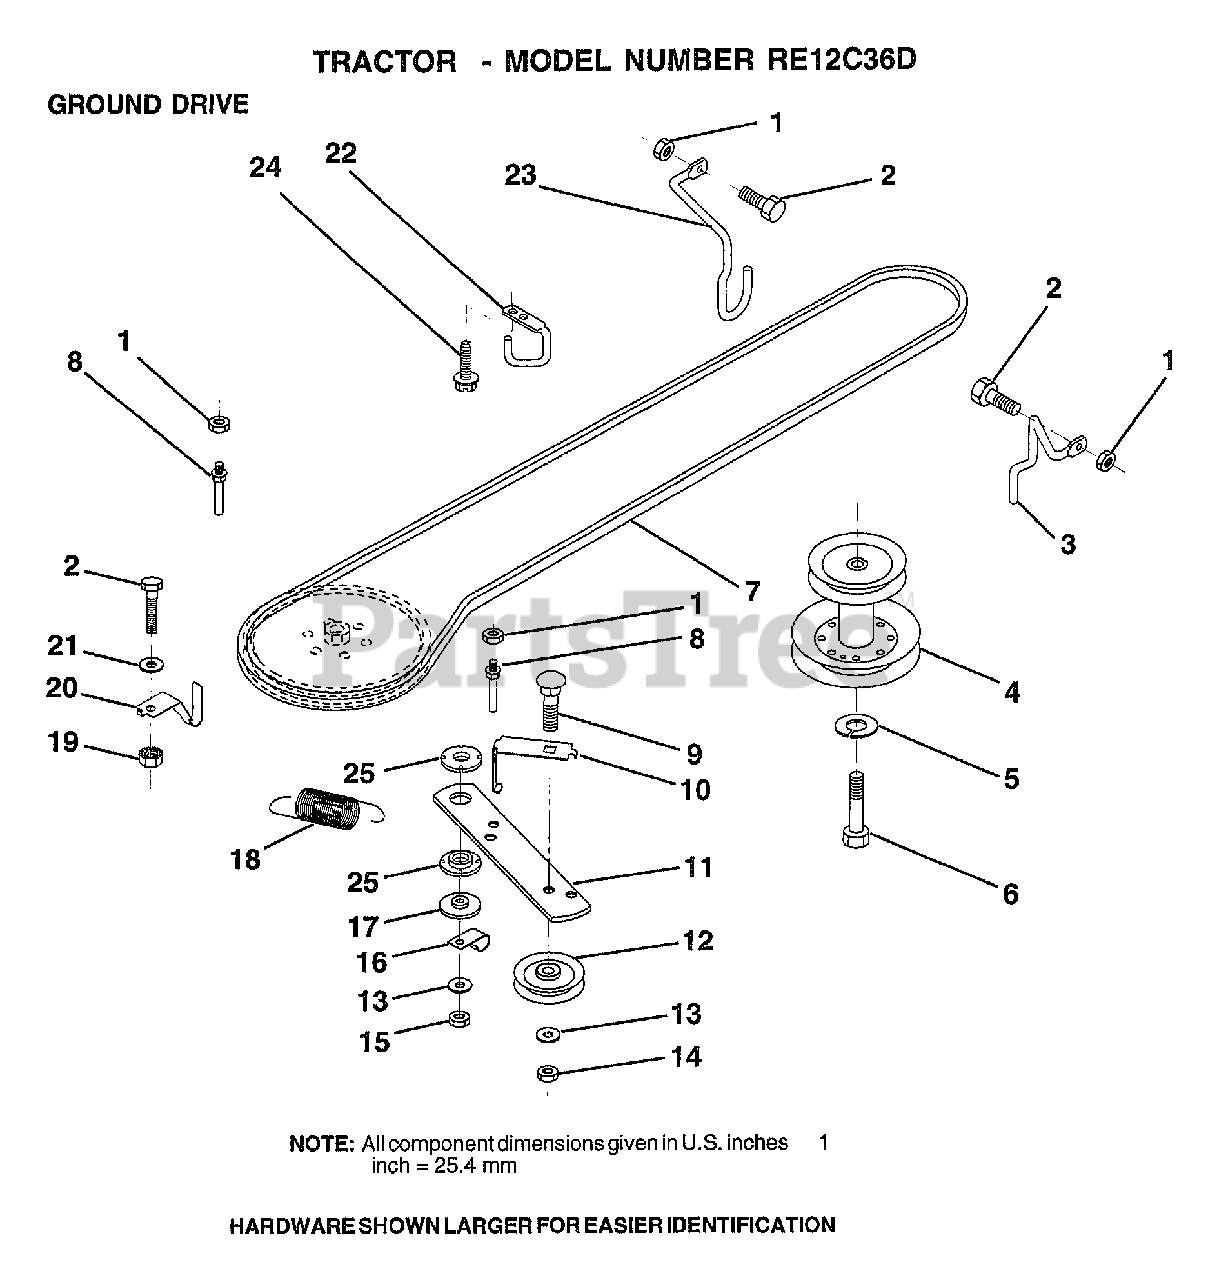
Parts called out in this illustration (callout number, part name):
2	BOLT
3	KEEPER RH
4	PULLEY.ENGINE.LR
5	LOCKWASHER
6	HEX BOLT
7	V BELT
8	"KEEPER,DRIVE BELT"
9	BOLT
10	"KEEP,IDLER DR BEL"
11	ARM-IDLER.DR.GRND
12	PULLEY.IDLER.FLAT
13	WASHER
14	LOCKNUT
16	"CLIP,INSULATOR"
17	SPACER
20	KEEPER.BELT.T/A
21	WASHER
22	"KEEPER,FRA DR BEL"
23	KEEPER MOWER LH
24	SCREW
25	BUSHING.NYLON
